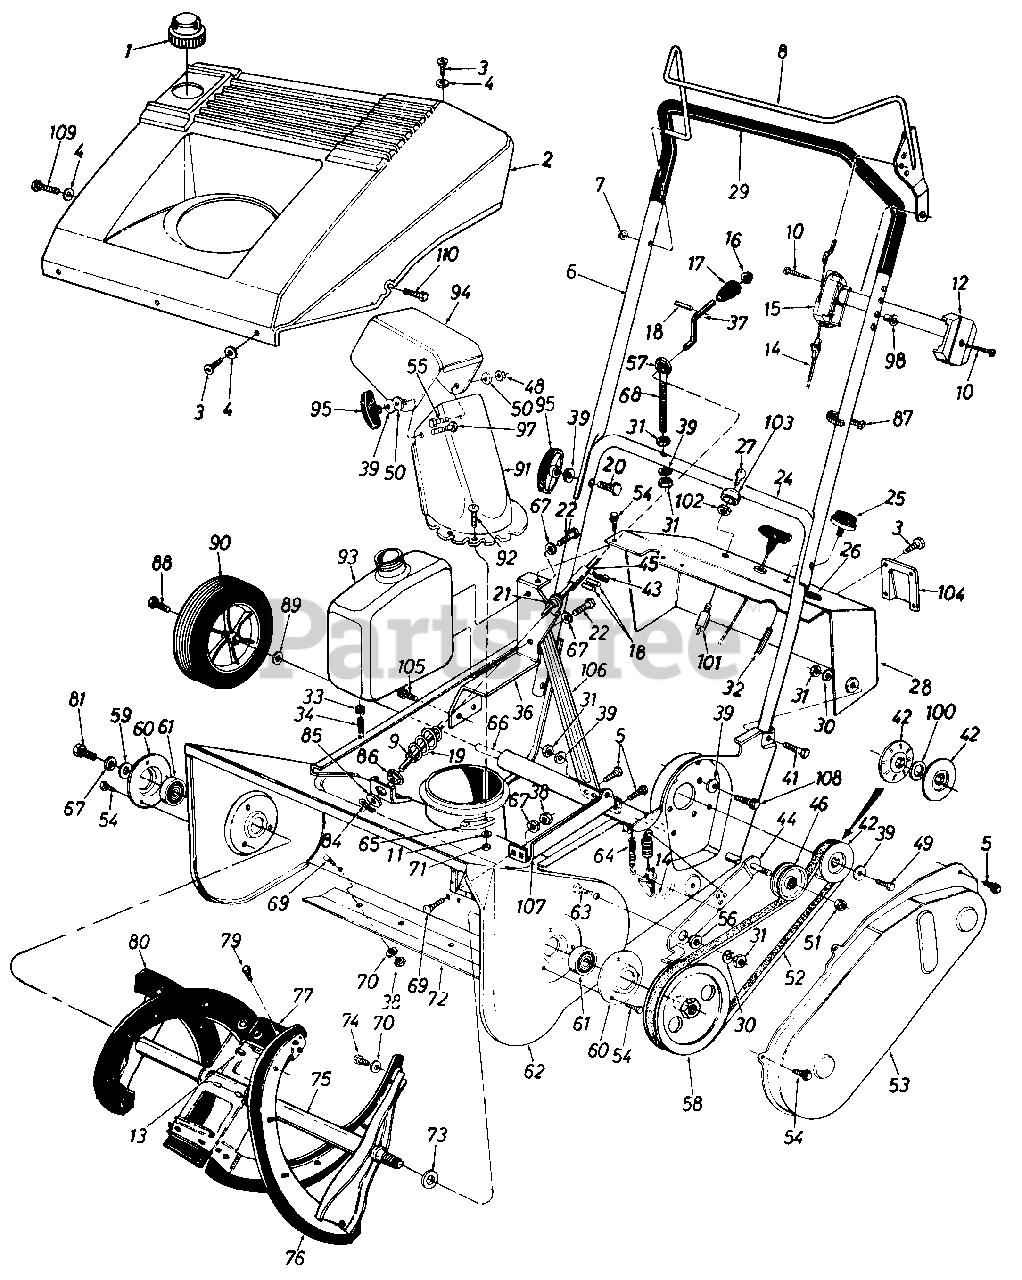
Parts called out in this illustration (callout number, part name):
1	Gas Tank Cap
2	Shroud
3	Hex B-Tap Scr. #10 x .5" Lg.
4	Fl-Wash. .203" I.D. x .41n
5	Hex L-Wash. Hd. AB-Tap 1/4 x .62" Lg.
8	Control Handle Ass'y.-L.H.
9	Fl-Wash. .385" l.D. x .62"
10	Truss Mach. Hi-B 0 Tap Scr. #12 x 1.5" Lg.
11	Fl-Wash. .281" I.D. x .5" O.D.
12	Control Panel Half
13	Pop Rivet .188" Dia.
14	Clutch Cable 35" Lg.
15	Control Panel Half
16	Push Cap 3/8" Rod
17	Knob-318" Dia. Hole
18	Roll Pin 1/8" Dia. x .63" Lg.
19	Lower Chute Crank Ass'y.
20	Curved Carriage Bolt 5/16-18 x 1.75" Lg.
21	Chute Crank Grommet
22	Hex Bolt 1/4-20 x .5" Lg.
24	Lower Handle
26	Plastic Plug
30	L-Wash. 5/16" l.D.
31	Hex Nut 5/16-18 Thd.
32	Primer Hose-9" Lg.
33	Hose Clamp-1/2" O.D.
34	Gas Line-16" Lg.
36	Gas Tank Support Brkt.
37	Upper Chute Crank
38	Hex Jam Nut 1/4-20 Thd.
39	Bell-Wash. .345" I.D. x .88"
41	Hex Bolt 5/16-18 x 1.5" Lg.
42	3/8" "V"-Pulley Half .625" I.D. x 6.0" O.D.
43	Hairpin Clip 3/8" Dia.
44	Idler Brake Brkt. Ass'y.
45	Spacer.38" I.D. x 1.12" Lg.
46	Fl-ldler w/Flanges 2.12" O.D.
48	Hex L-Nut 5/16-18 Thd.
49	Hex Bolt 5/16-24 x .75" Lg.
50	Fl-Wash. .344" I.D. x 1.25"
51	Hex Patch L-Nut 3/8-24 Thd.
52	V-Belt
54	Hex B-Tap Scr. 1/4" X .38" Lg.
55	Carriage Bolt 5/1 6-1 8 x .75"
56	Shld. Spacer .50" Dia. x .27"
57	Plastic Bushing .38" I.D.
58	1/2" "V"-Pulley 1/2-20 L.H.
59	Fl-Wash. 1/4" I.D. x .93" O.D.
60	Bearing Cup
61	Ball Brg. .669" l.D. x 1.574"
64	Extension Spring 1.12" Lg.
65	Chute Flange Keeper
66	Wheel Axle 20.6" Lg.
67	L-Wash. 1/4" I.D.
68	Eyebolt
69	Carriage Bolt 1/4-20 x .50"
70	Fl-Wash. .281" I.D. x .73"
71	Hex L-Nut 1/4-20 Thd.
72	Shave Plate
73	Fl-Wash. .510" I.D. x 1.0" O.D.
74	Hex Wash. B-Tap Scr. 1/4 x .62"
75	Auger Ass'y. 21 "
76	Rubber Spiral-L.H.
77	Rubber Paddle
79	Hex Wash. B-Tap Scr. #10 x .62" Lg.
80	Rubber Spiral-R.H.
81	Hex Wash. TT-Tap Cl-Scr. 1/4-20 x .75" Lg.
84	Cotter Pin 3/32" Dia. x .75"
85	Fl-Wash. .406" I.D. x 1.25"
86	Hex Bushing .385" I.D.
87	Cable Tie
88	Hex Tap Scr. 3/8-24 x .88" L9.
89	Fl-Wash. .510" I.D. x .75"
90	7" Wheel & Tire Ass'y.
91	Lower Chute
92	Truss Mach. Scr. 1/4-20 x .75"
93	Fuel Tank-Two Qt.
94	Upper Chute
95	Knob Handle Ass'y.
97	Carriage Bolt 5/16-18 x 1"
98	Control Disc Pin
100	Fl-Wash. .635" I.D. x .93" O.D.
101	Key Switch
102	Ignition Switch Nut 5/8-32 Thd.
103	Ignition Switch Cap
104	Choke Cover
105	Hex Wash. Hd. Tap Scr. 1/4-.5" Lg.
108	Hex Bolt 16-18 x 5/8" Lg.
109	Pan Hd. Tap Scr. #10 x 1.25" Lg.
110	Hex Wash. Hd. Tap Scr. 1/4-20 x1" Lg.
